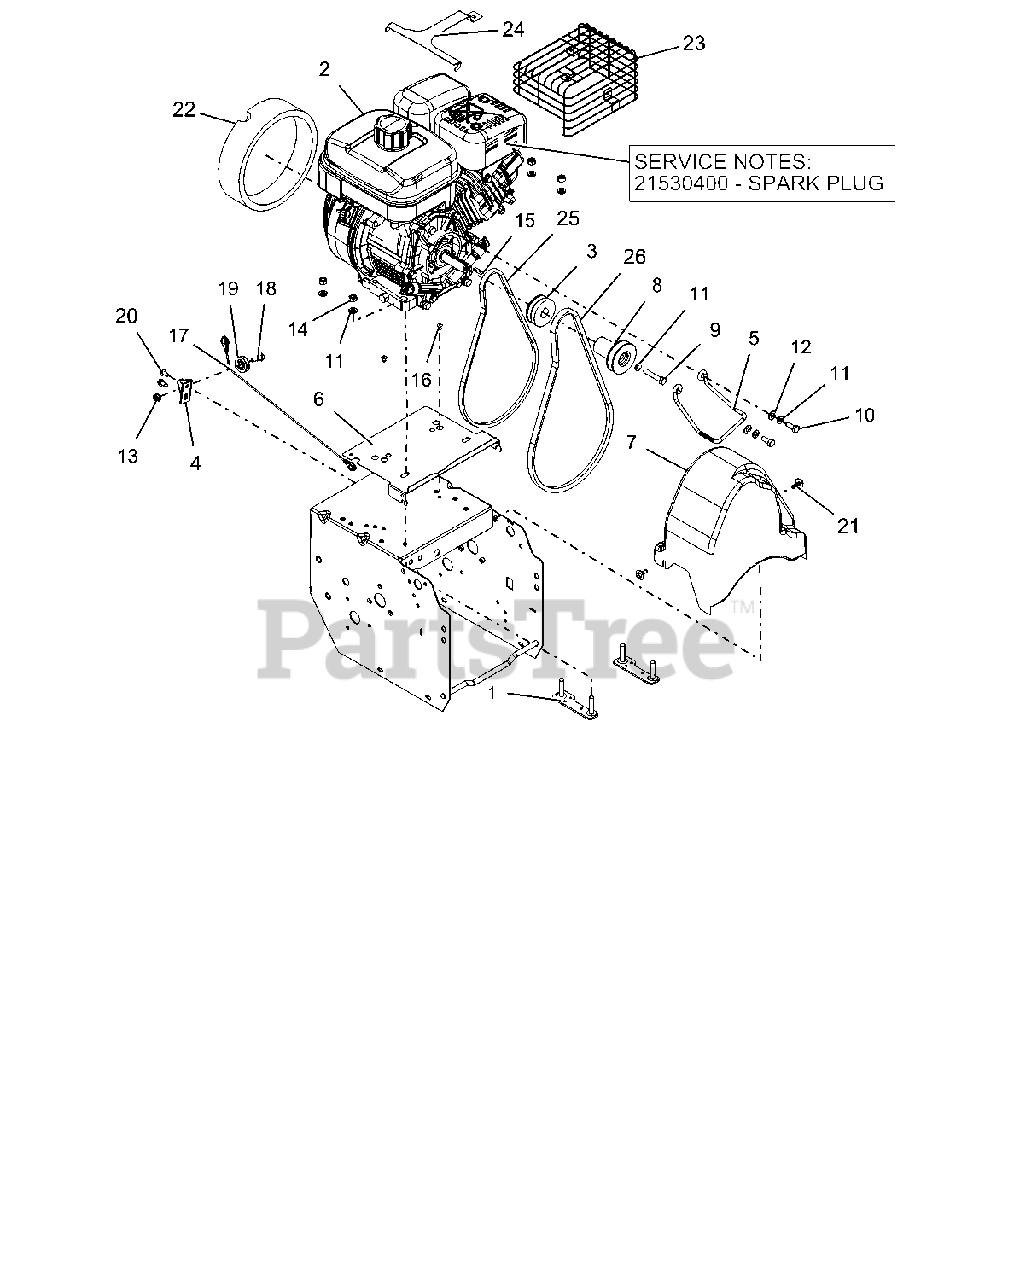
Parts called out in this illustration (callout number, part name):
1	WLDMT, STRAP ENGINE BOLT
2	ENGINE, SUBARU - EX17 120V ALL SEASON RECOIL
2	SPARK PLUG
3	PULLEY, TRACTION
4	BRKT, CABLE PULLEY
5	FINGER, BELT
6	BAFFLE, COMPACT
7	COVER, BELT
8	SHEAVE, AUGER DRIVE
9	BLT-HEX .31-24X1.75 GR5 YWZC
10	BLT-HEX .31-24X.75 GR5 YWZC
11	WSHR-LK .31X.097 HVY YWZC
12	WSHR-FL-STL.344X.688X.065YWZC
13	NUT, LK-CTR-FLG .25-20 YWZC
14	NUT-HEX .31-18 YWZC
15	KEY-SQ .188X.188X.750
16	RVT-POP .187x.250 (#64) YWZC
17	CABLE, LOWER TRACTION
18	BOLT, SHLDR -.375 X .375 X .25-20
19	PULLEY, CABLE
20	SCR-TAP .25-20X.50 HWH TR YWZ
21	SCR, TAP .25-20 X.5 CAPTIVE
22	COVER, FOAM - SUBARU RECOIL
23	GUARD, MUFFLER - SUBARU
24	GUARD, SNO - ASUBARU EX17
25	V-BELT, 3L-WRAPPED CLUTCHING
26	V-BELT, HA-Raw Edge Laminated
